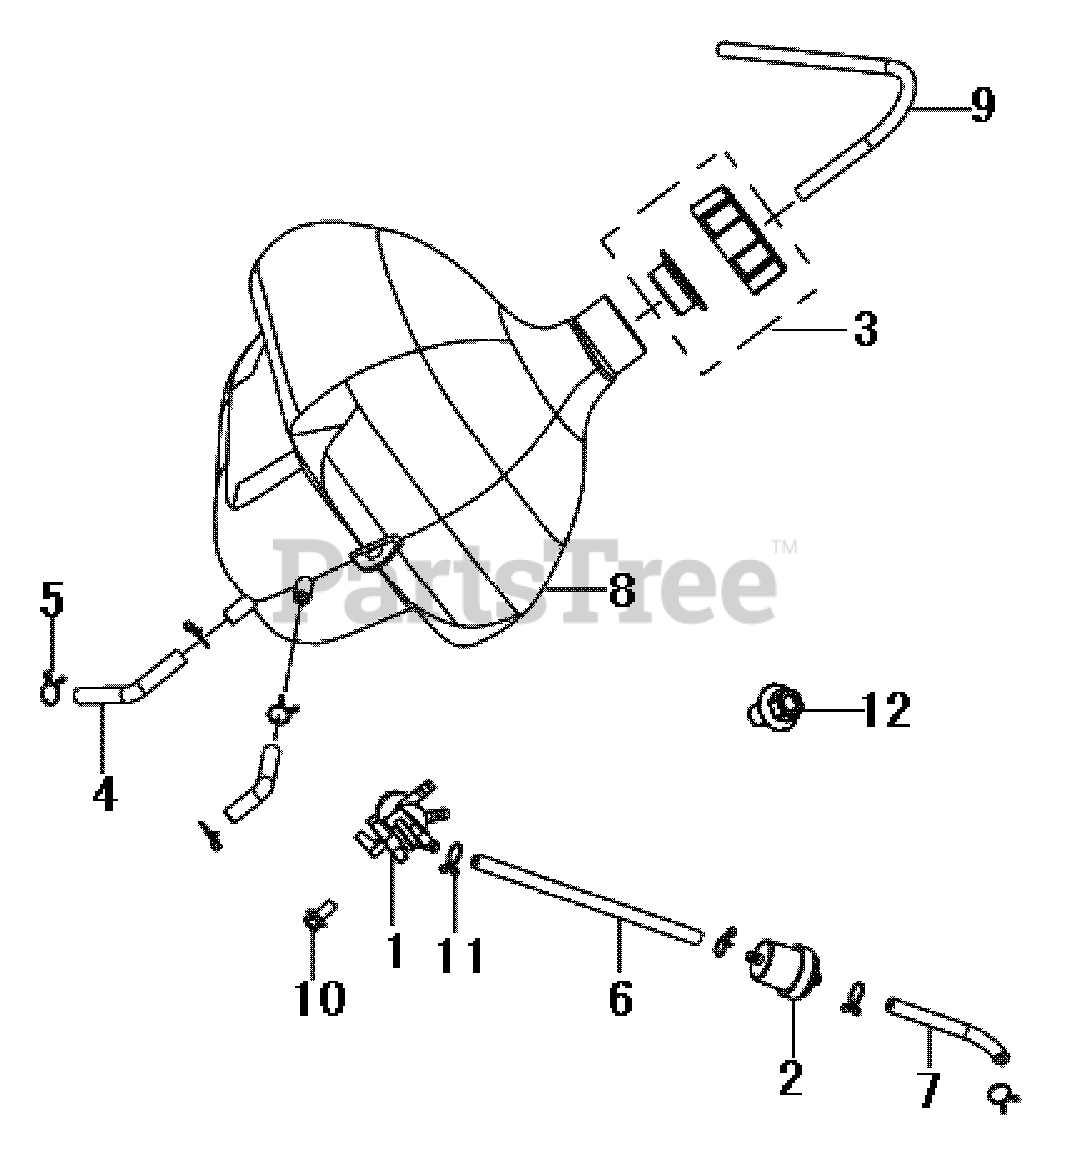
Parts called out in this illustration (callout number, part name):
1	FUEL VALVE ASSY.
2	FUEL FILTER ASSY.
3	FUEL TANK CAP ASSY.
4	FUEL LINE
5	CLAMP, FUEL LINE
6	FUEL LINE
7	FUEL LINE
8	FUEL TANK
11	CLAMP, FUEL LINE
